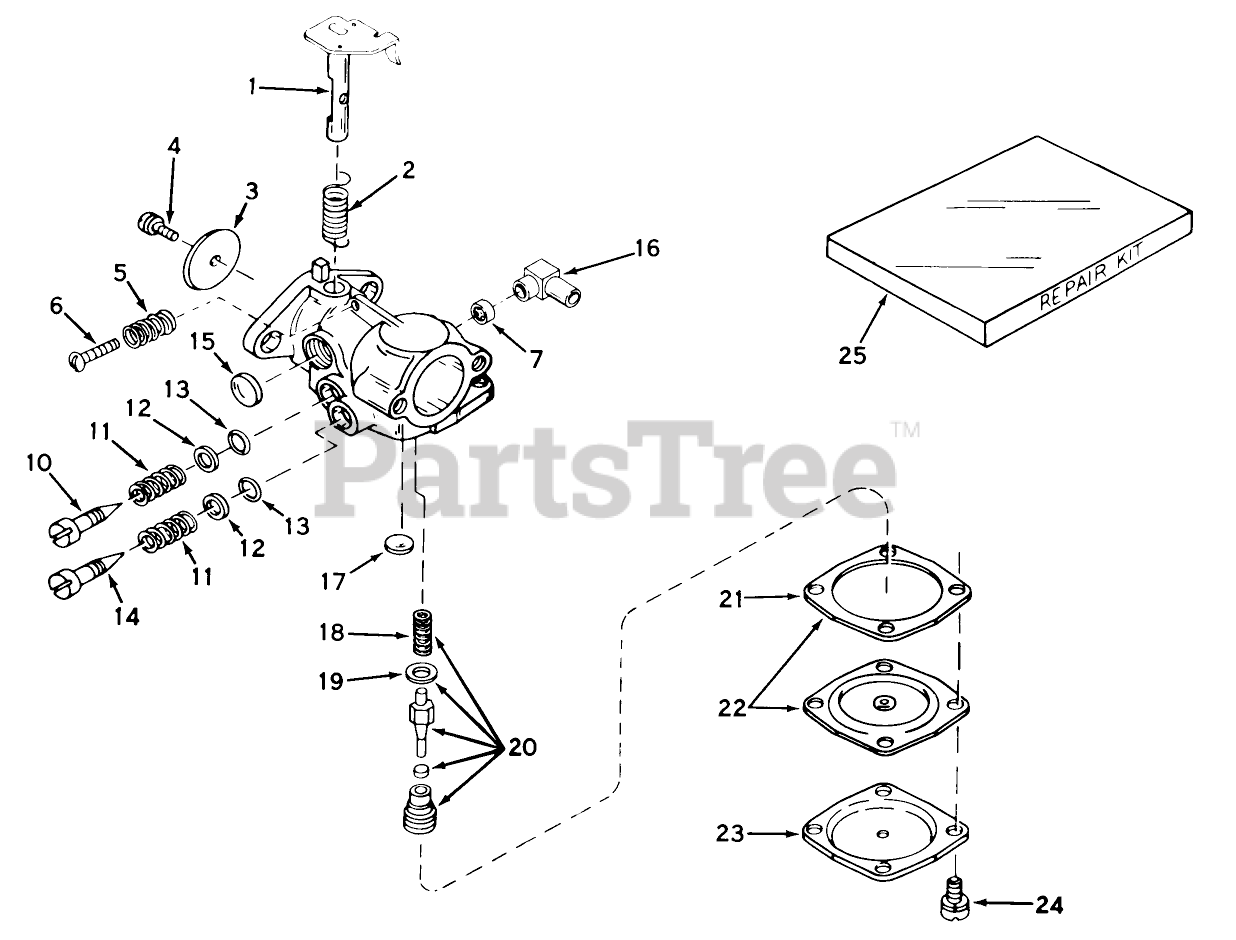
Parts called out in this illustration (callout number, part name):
1	Shaft Lever Assy.
2	Spring, Throtte Return
3	Shutter, Throttle
4	Screw-Shutter
5	Spring-Tension
6	Screw-Throttle Crack Screw / Idle Speed
7	Valve Check
10	Screw, Idle Adjustment
11	Spring
12	Washer
13	ORing
14	Screw, Main Adjustment
15	Plug-Welch, Idle Mixture Well
16	Nipple, Fuel Inlet
17	Plug Welch
18	Spring, Needle Valve
19	Gasket-Valve Seat
20	Needle, Valve, Seat Gasket
21	Gasket-Diaphragm
22	Diaphragm Ass. (Incl. No. 21)
23	63561/33165A O"HITC
24	Screw, Diaphragm Cover
25	Repair Kit
